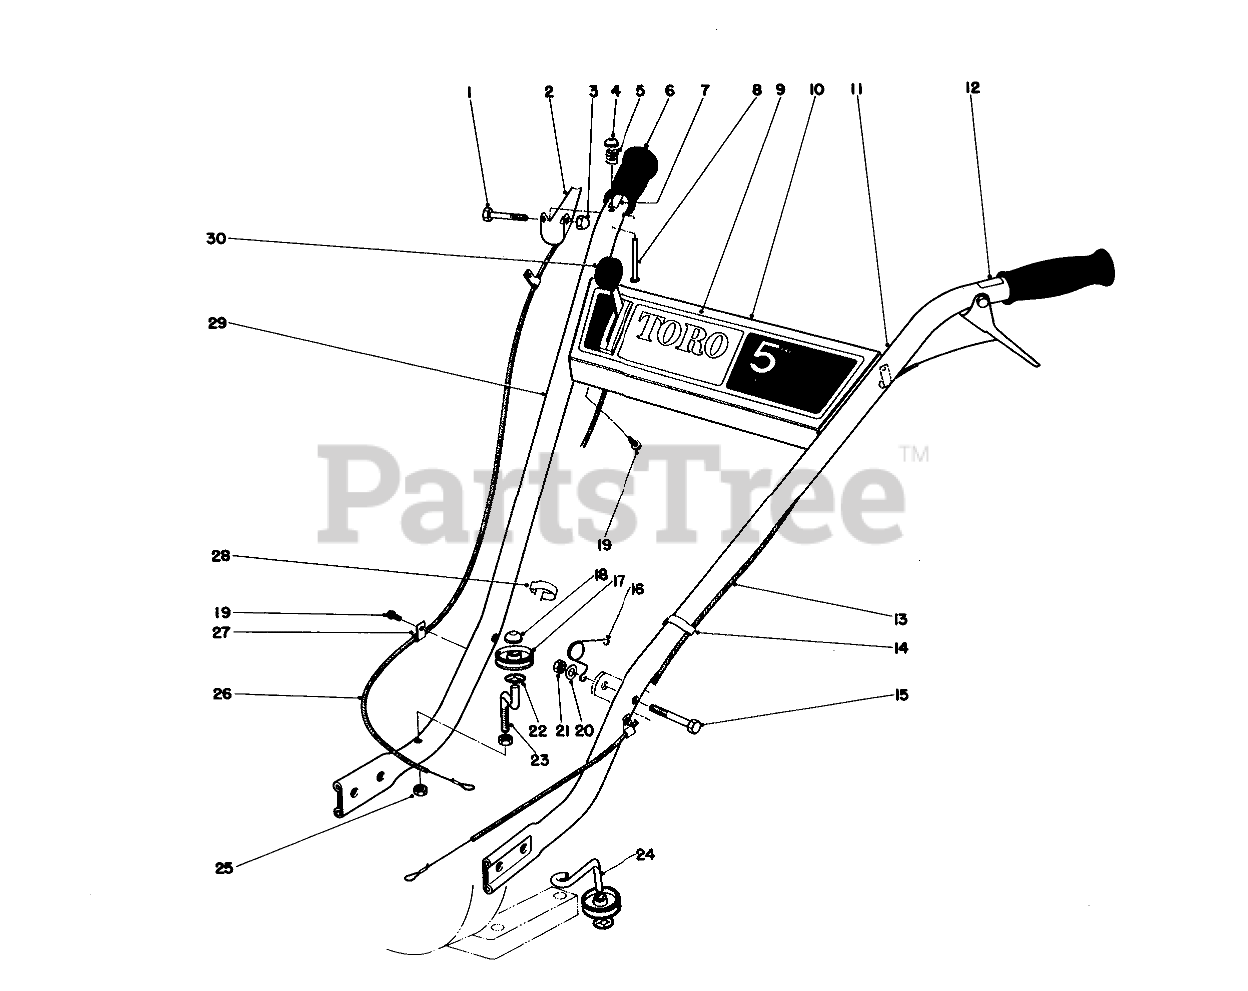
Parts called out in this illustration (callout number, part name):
1	SCREW-HH
2	LIFTBAIL
3	NUT-CAP
4	Push-On
5	COMPRESSION SPRING
6	Hand Grip
7	Decal-Fwd.
8	LOCK PIN
9	Decal-Escutcheon
10	Escutcheon Panel
11	Handle L.H.
12	Decal Rev.
13	REV CABLE ASM
14	BODEN CLIP
15	SCREW-HH
16	Spring-Torsion
17	Pulley Cable
18	RETAINER PUSH ON
19	SCREW-HWHTF
20	WASHER-PLAIN
21	NUT-LOCK, CONE
22	PUSH ON RETAINER
23	Spindle-Fwd.
24	Spindle-Rev.
25	LOCKNUT
26	FWD CABLE ASM
27	3/16 SUPPORT
28	Boden Clip
29	RH HANDLE
30	THROTTLE CONTROL
